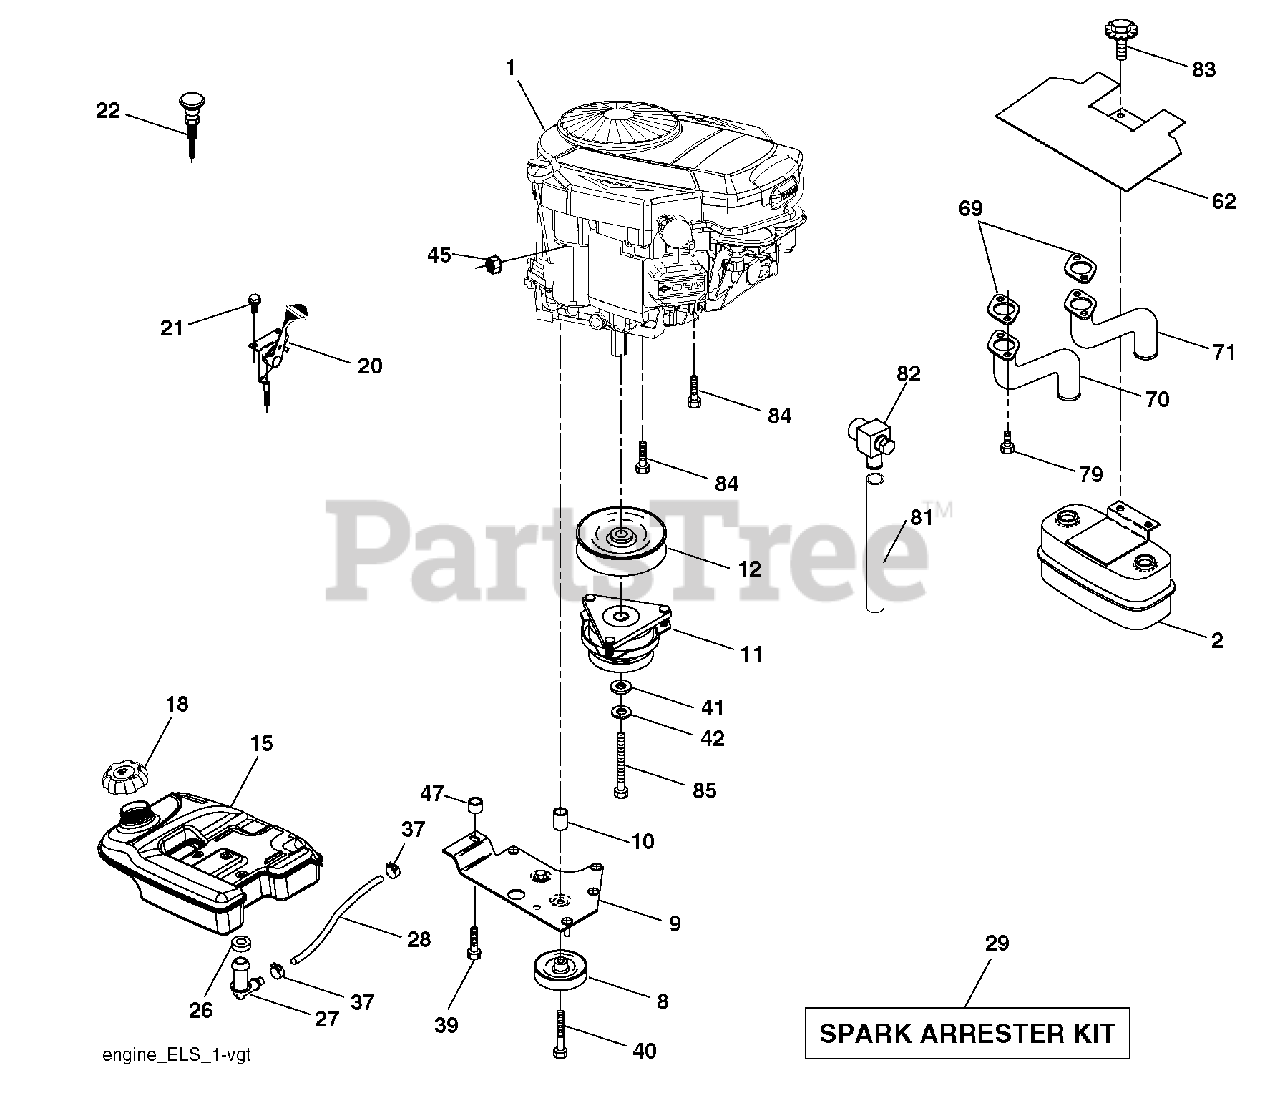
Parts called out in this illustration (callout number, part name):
2	Muffler Side
8	Pulley V-Idler
9	Keeper Asm. Belt Engine VGT
10	Bushing
11	Clutch Electric
12	Pulley Engine VGT Elect Clutch
15	Tank Fuel Rear 5.0
18	Cap Asm. Fuel
20	Control Throttle
21	Screw HwHd Hi-Lo #13-16 x 3/4
22	Control Choke
26	Bushing
27	Stem Tank Fuel
29	Spark Arrester Kit
31	Clip
37	Clamp Hose
39	Screw TT 3/8-16 x 2-1/4 unc
40	Screw TT 3/8-16 x 4 unc
41	Washer 1-1/2 OD x 15/32 ID x.250
42	Washer Lock 7/16
43	Bolt Hex 7/16-20 x 3.75 Gr. 5
45	Nut Keps Hex 1/4-20
47	Spacer
62	Shield Heat Muffler CV-Intek
69	Gasket
70	Tube Exhaust LH
71	Tube Exhaust RH
79	Screw Socket Head 5/16-18 x 1
81	Tube Drain Oileasy
82	Plug Oil Drain
83	Bolt 5/16-18 Unc x 1-3/4 W/Sems
84	Screw Thdrol 3/8-16 x 1-1/2
